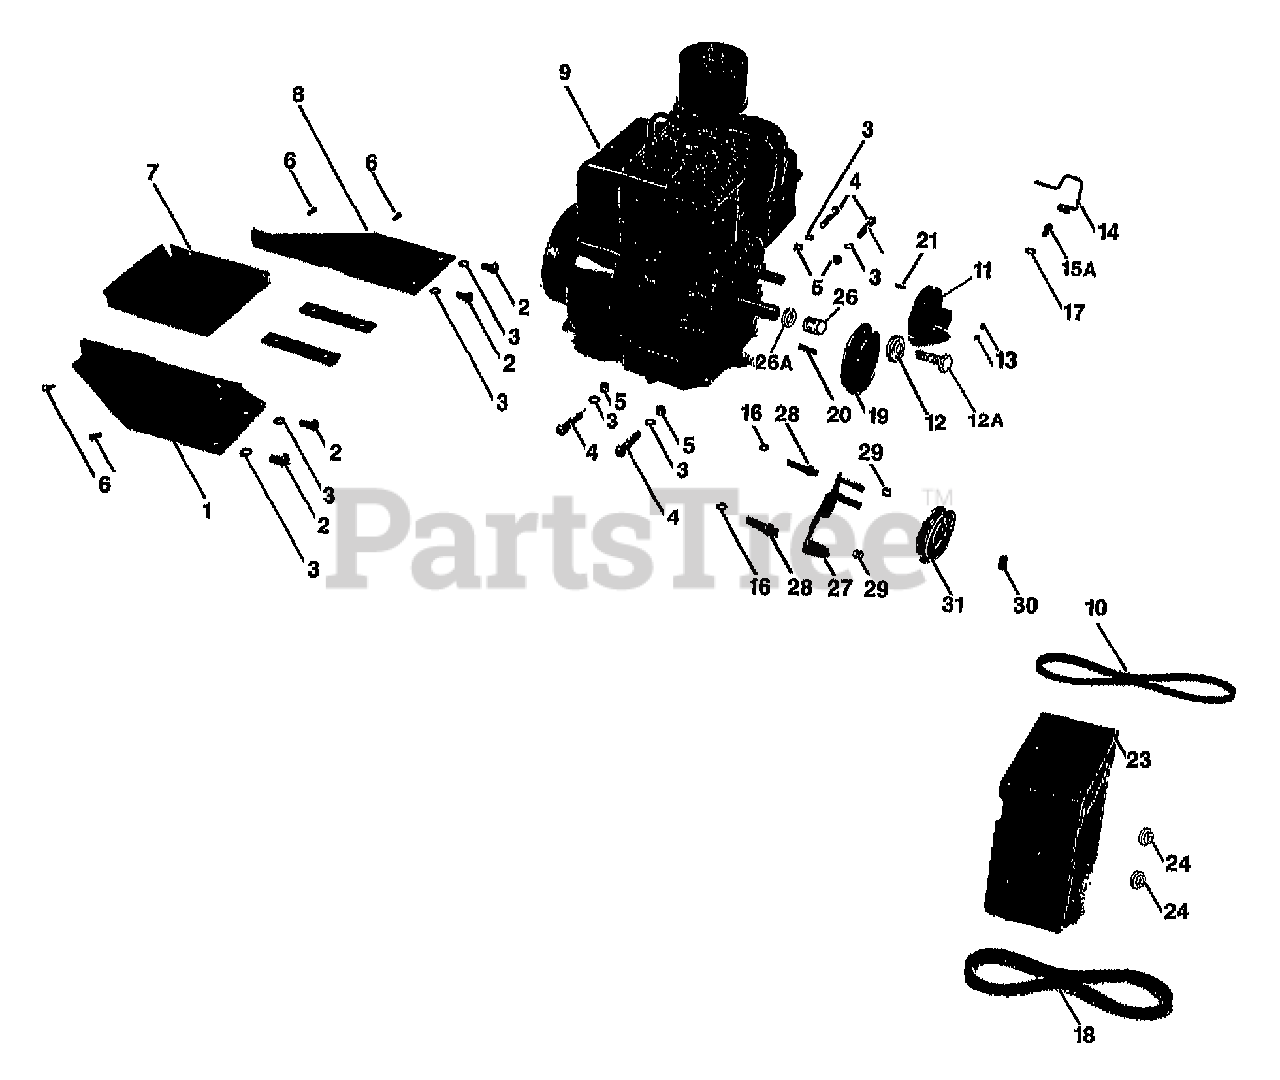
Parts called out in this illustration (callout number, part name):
1	BRKT-ENG LT P4
2	SCR-HHC 5/16-18X.75 GR 5 ZP
3	WASHER-LK .312 ZP
4	SCR-HH 5/16-18X1.5 G5 ZP
5	NUT-HEX 5/16-18 ZP
6	SCR-HH SEMS 10-32 X .5 ZP (SEMS - WITH PERMANENT WASHER)
7	PAN-ENG BRKT PNT
8	BRKT-ENG RT PNT
9	ENGINE B&S STANDARD RECOIL START.
9	ENGINE B&S ELECTRIC START.
10	BELT-V (SEE V-BELT SET BELOW)
11	PULLEY-ENG MACH
12	WASHER-.827X.331X.098 (CONCAVE SURFACE FACES FORWARD PULLEY)
12A	SCR-HH 5/16-24X.75 G5 ZP (ATTACHES FORWARD PULLEY)
13	SCR-SS 1/4-20 X .25 (SECURES REVERSE ENGINE PULLEY)
14	GUIDE-BELT FWD
15A	SCR-HWH 1/4-20 X .75 STH
16	WASHER-LK .25 ZP
17	WASHER-FLAT 1/4 SAE
18	BELT-V GROOVE FWD SMFRAME (SEE V-BELT SET BELOW)
19	PULLEY-ENGINE MACH
20	KEY-.188 SQX1.0
21	KEY-WOODRUFF #5
23	SHROUD-BELT PNT
24	NUT-HFLK 5/16-18 ZP
26	SPACER-ENGINE PULLEY (ON FORWARD PTO SHAFT BETWEEN ENGINE & FORWARD PULLEY)
26A	SHIM-1.0X.7656X.031 (ON FORWARD PTO SHAFT BETWEEN ENGINE & SPACER)
27	BRKT-IDLER WELD PNT
28	STUD-5HP (B&S PART)
29	NUT-LK 1/4-20
30	NUT-H/LK 3/8-16
31	IDLER-"V" GROOVE (INTERNAL BUSHING TYPE)
